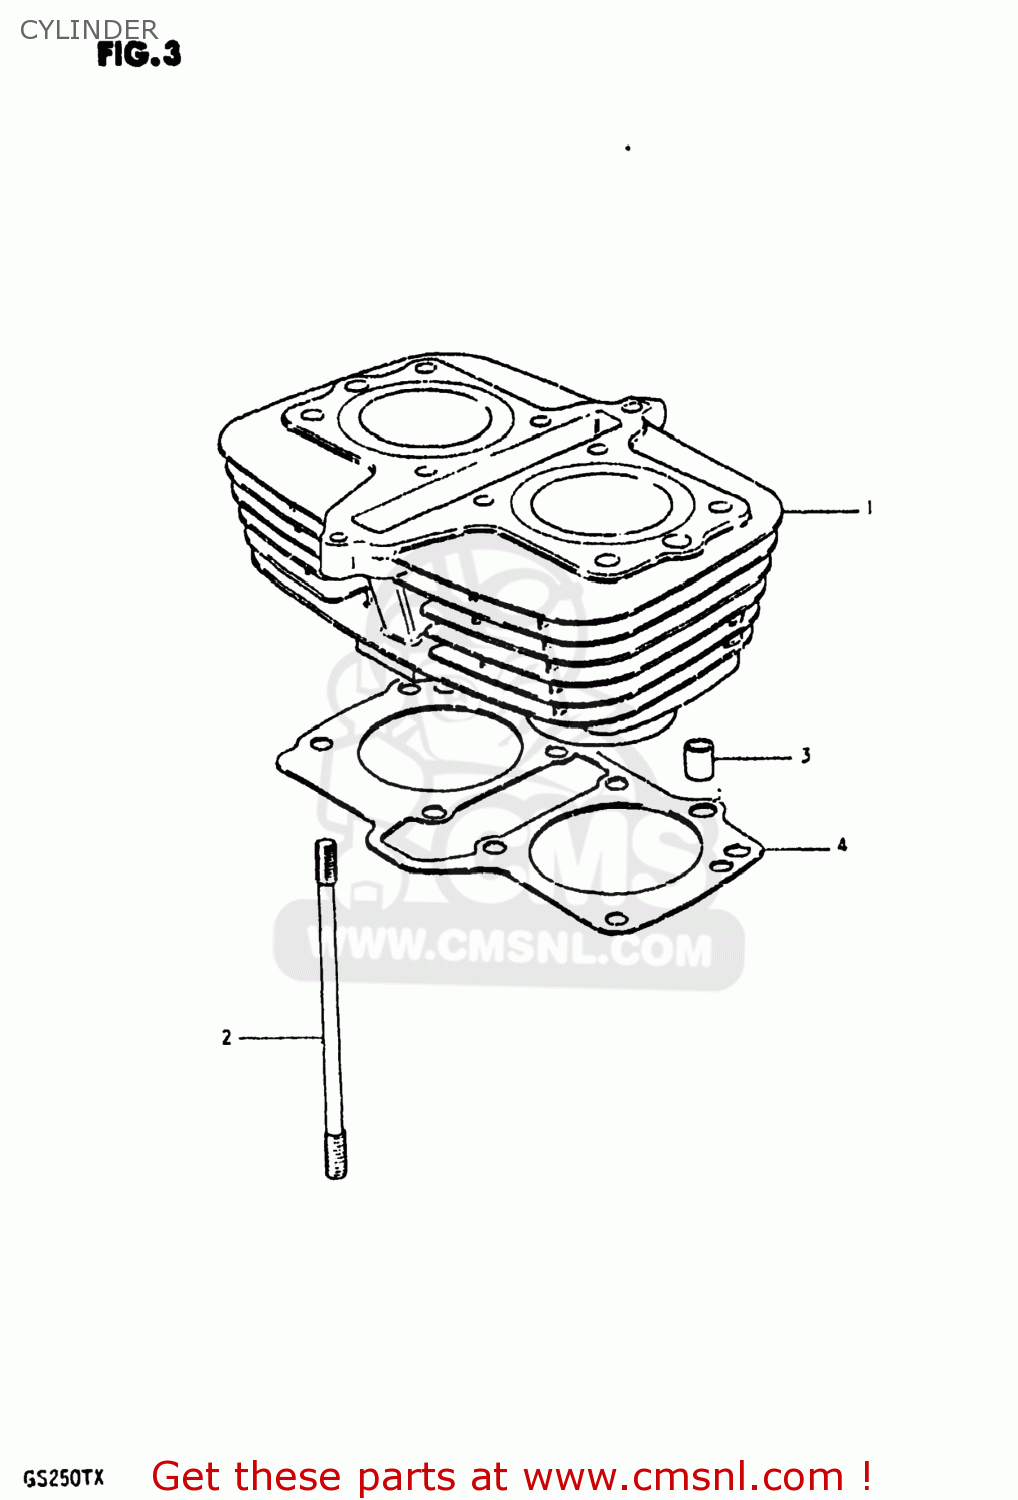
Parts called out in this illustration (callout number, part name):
1	CYLINDER
2	STUD
3	PIN
4	GASKET,CYLINDER (MCA)
